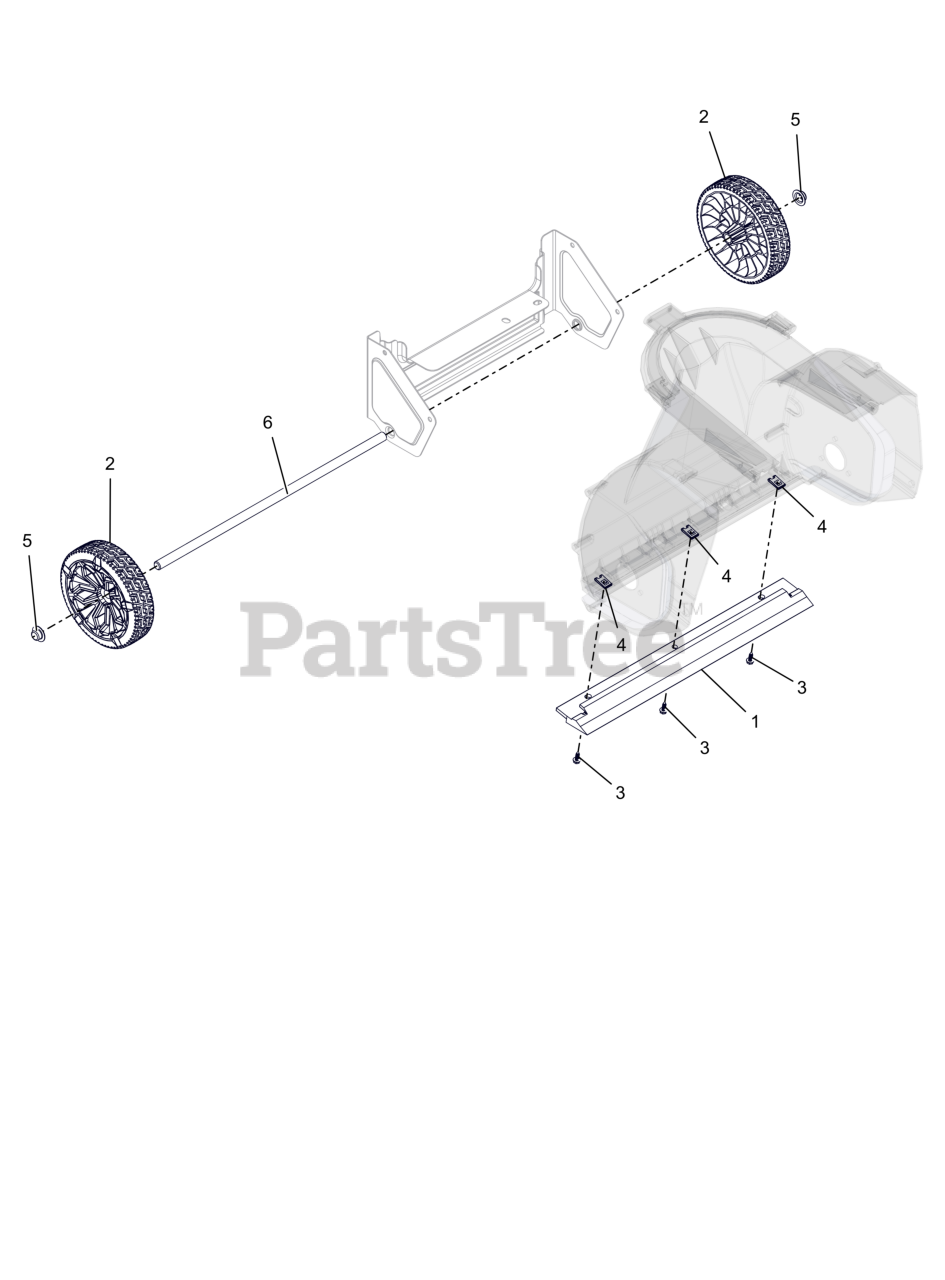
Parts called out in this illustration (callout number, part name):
1	KIT, SCRAPER REPLACEMENT 18IN
2	WHEEL, ASM
3	#10X5/8 SHEETMETAL SCR
4	NUT, CLIP ON - #10 NOSLIP
5	NUT, PUSH - AXLE
6	AXLE, WHEEL
